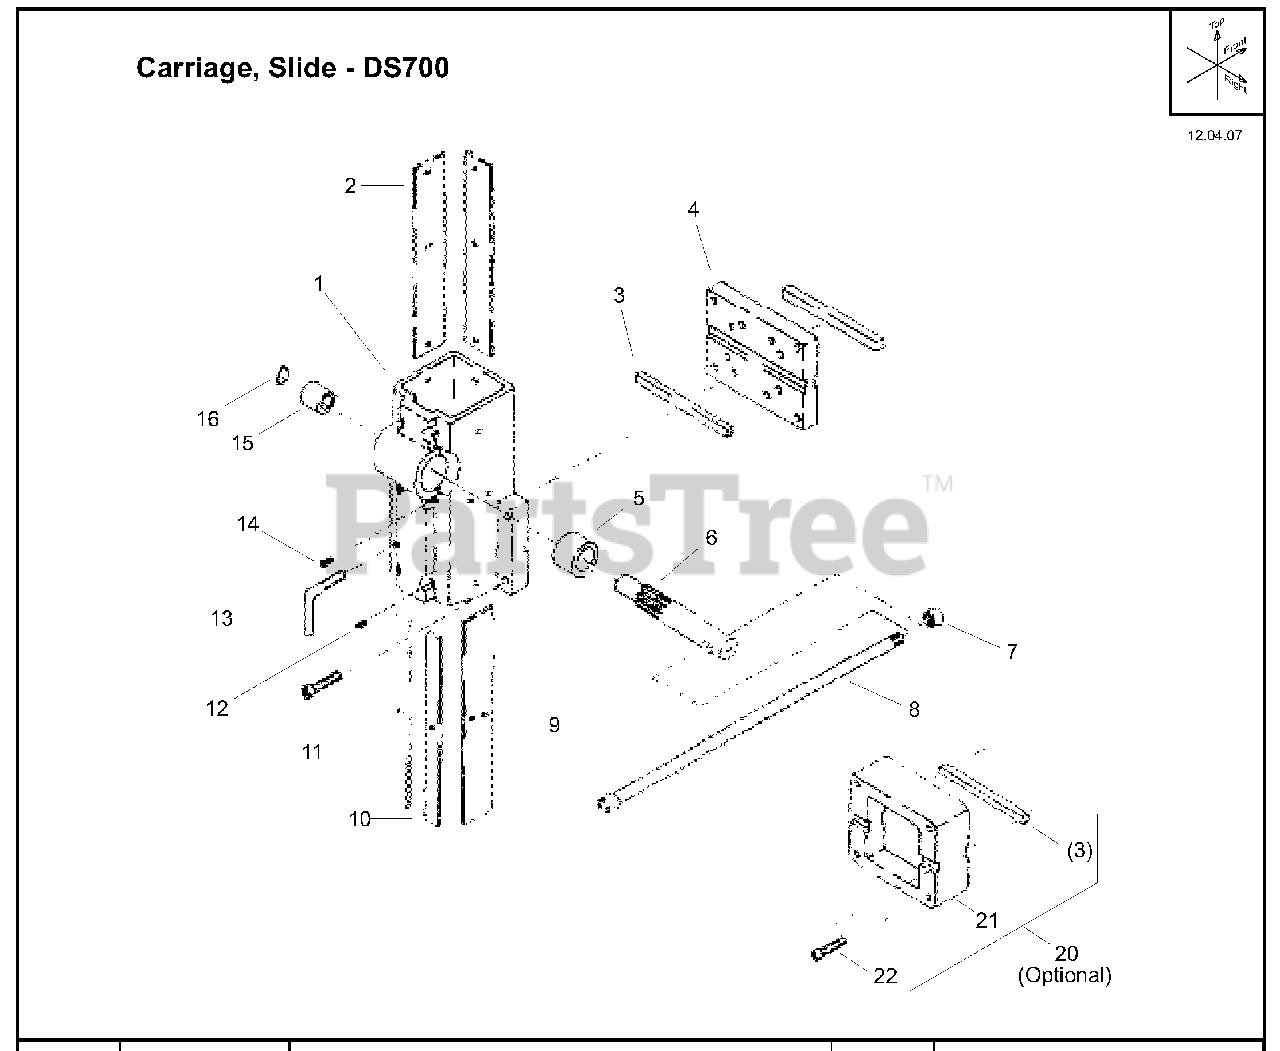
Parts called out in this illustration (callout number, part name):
1	Body, Carriage - Husq Orange
2	Plate, Wear, Wide - Fixed
3	Key, 3/8" Sq x 5.0
4	Plate, Motor Adapter
5	Bushing, Bronze - 1"ID x 1-1/4 OD x 7/8
6	Pinion, Slide Handle Type
7	Cap, Slide Handle
8	Slide, Handle
9	Plate, Wear, Wide - Adjustable
10	Plate, Wear, Narrow - Adjustable
11	Capscrew, Soc Hd 3/8-16 x 1-1/2"
12	Screw, Set, Soc 1/4-20 x 3/8"
13	Knob, Carriage Lock DS700
14	Mach Screw, Flat Hd 10-32 x 3/8" Brass
15	Bushing, Bronze - 5/8"ID x 7/8 OD x 7/8
16	Ring, Retaining
20	Kit, 2" Spacer Block, DS700
21	Block, 2" Spacer, DS700 Husq Orange
22	Capscrew, Soc Hd 3/8-16 x 3-1/2"
